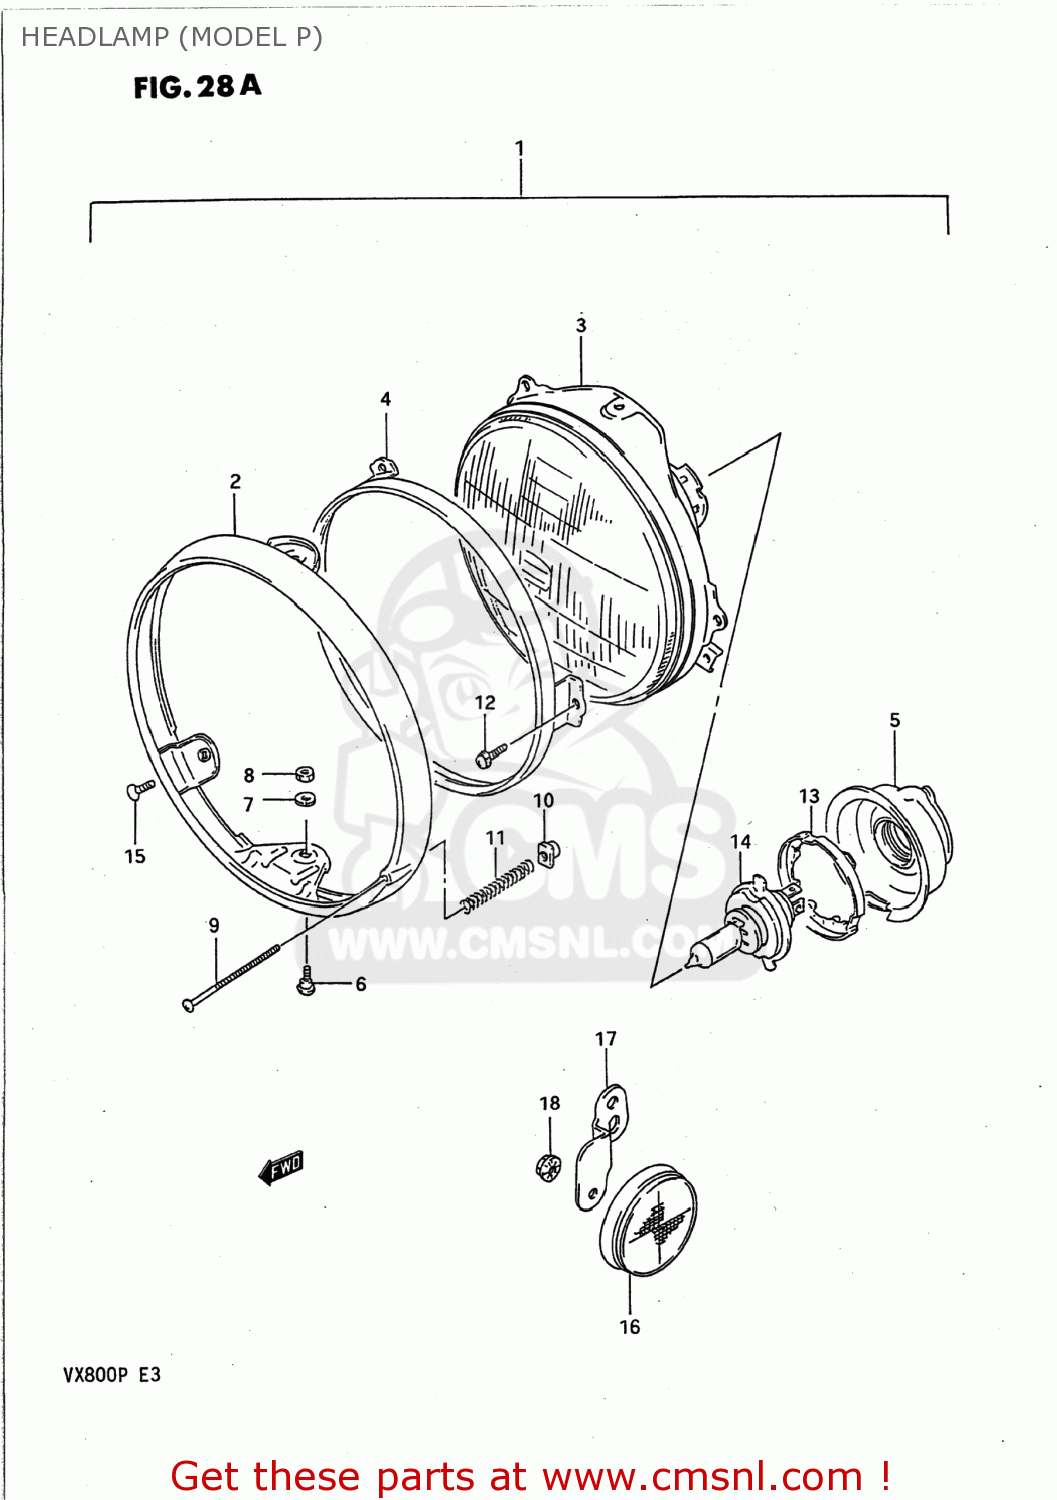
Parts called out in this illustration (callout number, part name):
1	HEADLAMP ASSEMBLY
2	RIM,HEADLAMP
3	LAMP UNIT
4	RETAINING RING
5	COVER,SOCKET
6	H/LAMP LENS UNIT FITING SCRE
7	LOCK WASHER
8	NUT
9	SCREW,HEADLAMP ADJUST
10	NUT
11	SPRING,ADJUSTING
12	SCREWM4X0.7X10
13	SETTING,BULB
14	BULB(12V60/55W,H4)
15	SCREW 5X12
16	REFLECTOR,REFLEX FR
17	BRACKET,SIDE REFLECTOR
18	NUT
